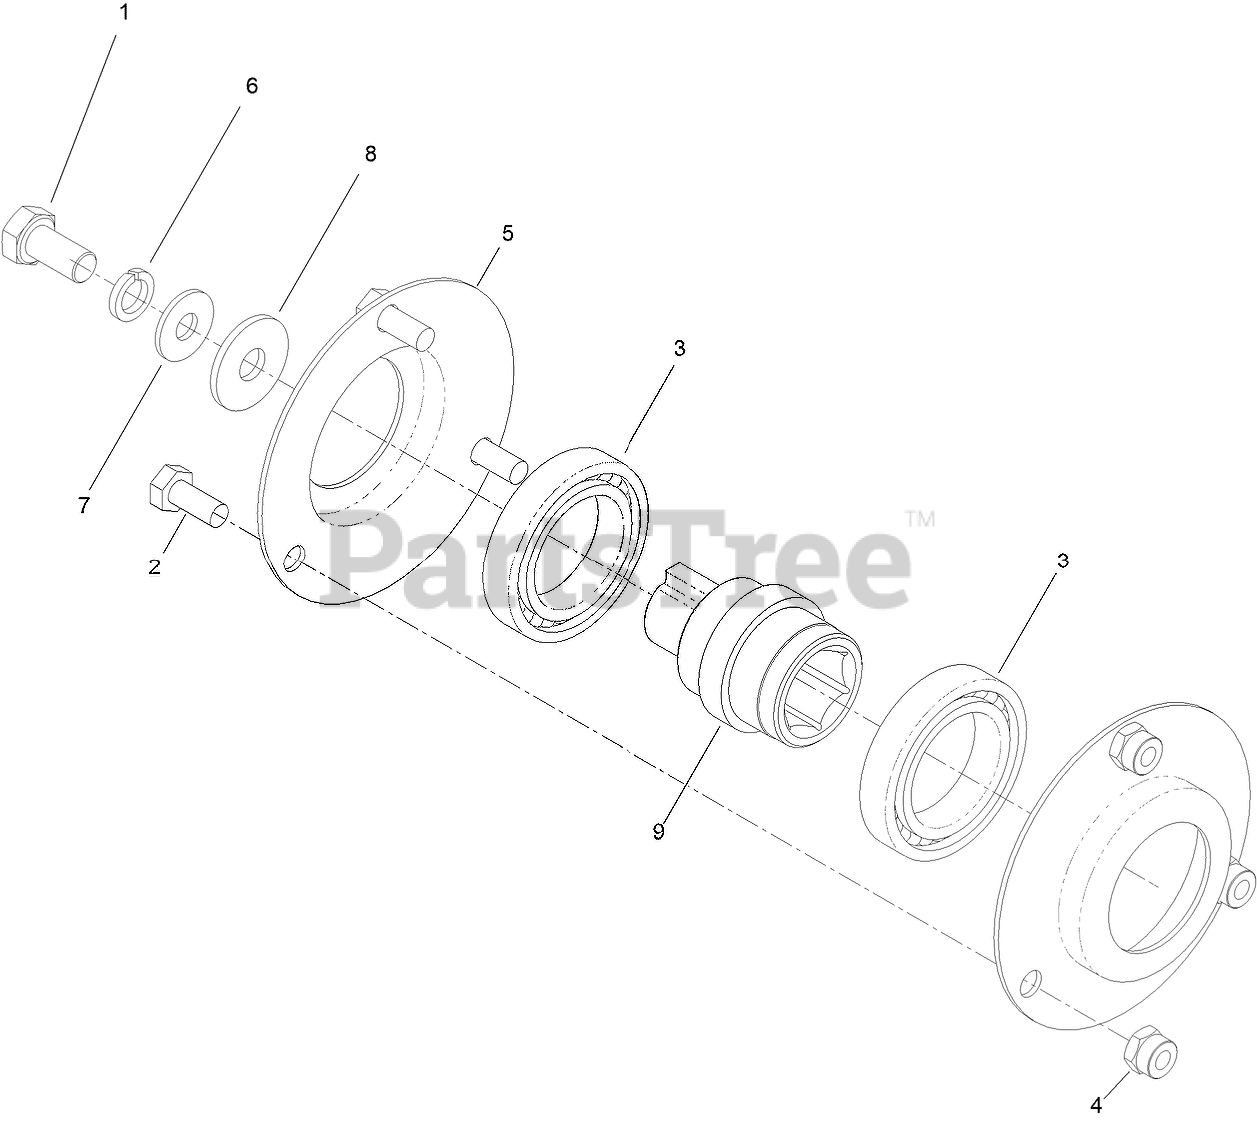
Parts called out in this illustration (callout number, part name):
1	BOLT-HEX
2	BOLT-HEX
3	BEARING
4	NUT-NYLOC
5	FLANGE
6	WASHER- LOCK, SPRING
7	WASHER
8	WASHER
9	COUPLER
